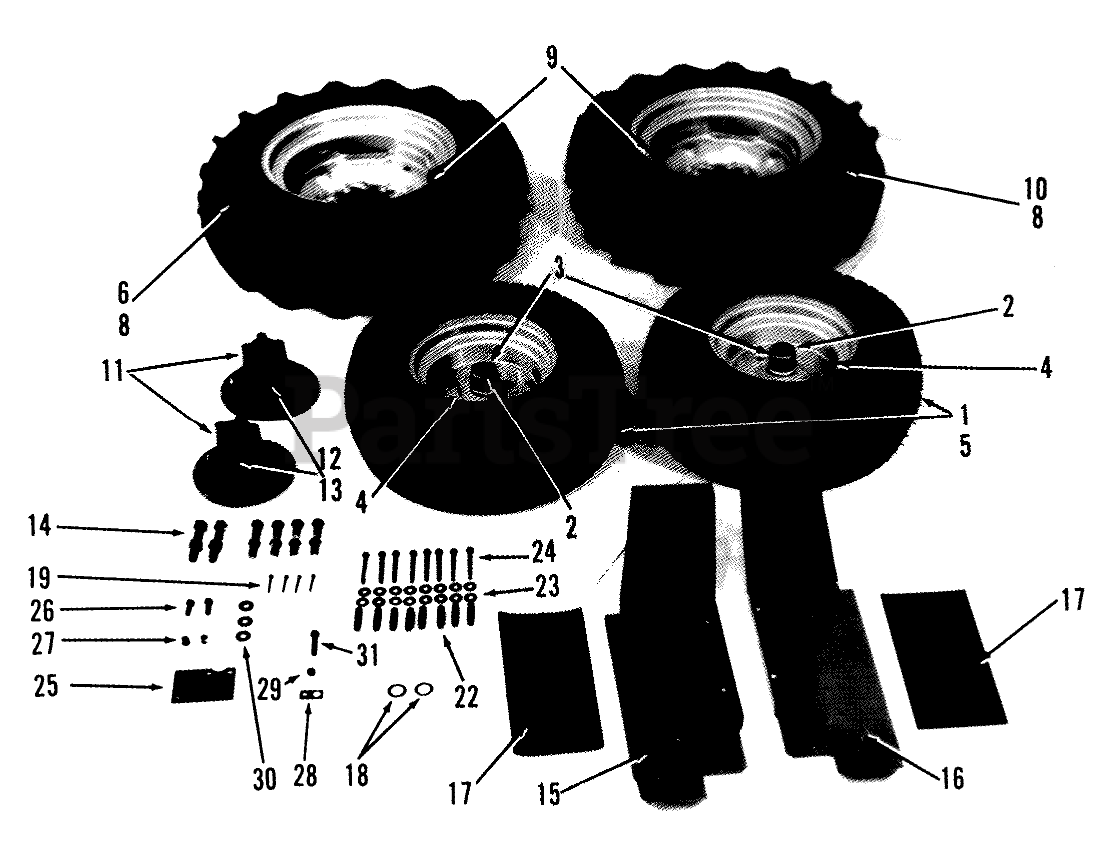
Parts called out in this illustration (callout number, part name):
1	Wheel & Tire 20 x 8.00-10
2	BEARING-RADIAL FLNGE
3	ZERK-GREASE
4	VALVE
6	RH Ag Wheel & Tire 27 x 8.50-15
8	Tube (Service Only)
9	VALVE TUBELESS
10	LH Ag Wheel & Tire 27 x 8.50-15
11	REAR HUB R
12	SS-SQ HD3/8-16X1 1/2
13	Nut
14	LUG BOLT WHEEL 7/162
15	FOOTREST RH R
16	FOOTREST LH R
17	Sandpaper Mat
18	WASHER
19	COTTER PIN-4
22	TUBE-CLUTCH SPACER
23	Washer 5/16
24	Pin-Cotter
25	PLATE IDLER R
26	BOLT
27	NUT
28	PLATE SPRING ANCHOR
29	Nut
30	Washer
31	Bolt
